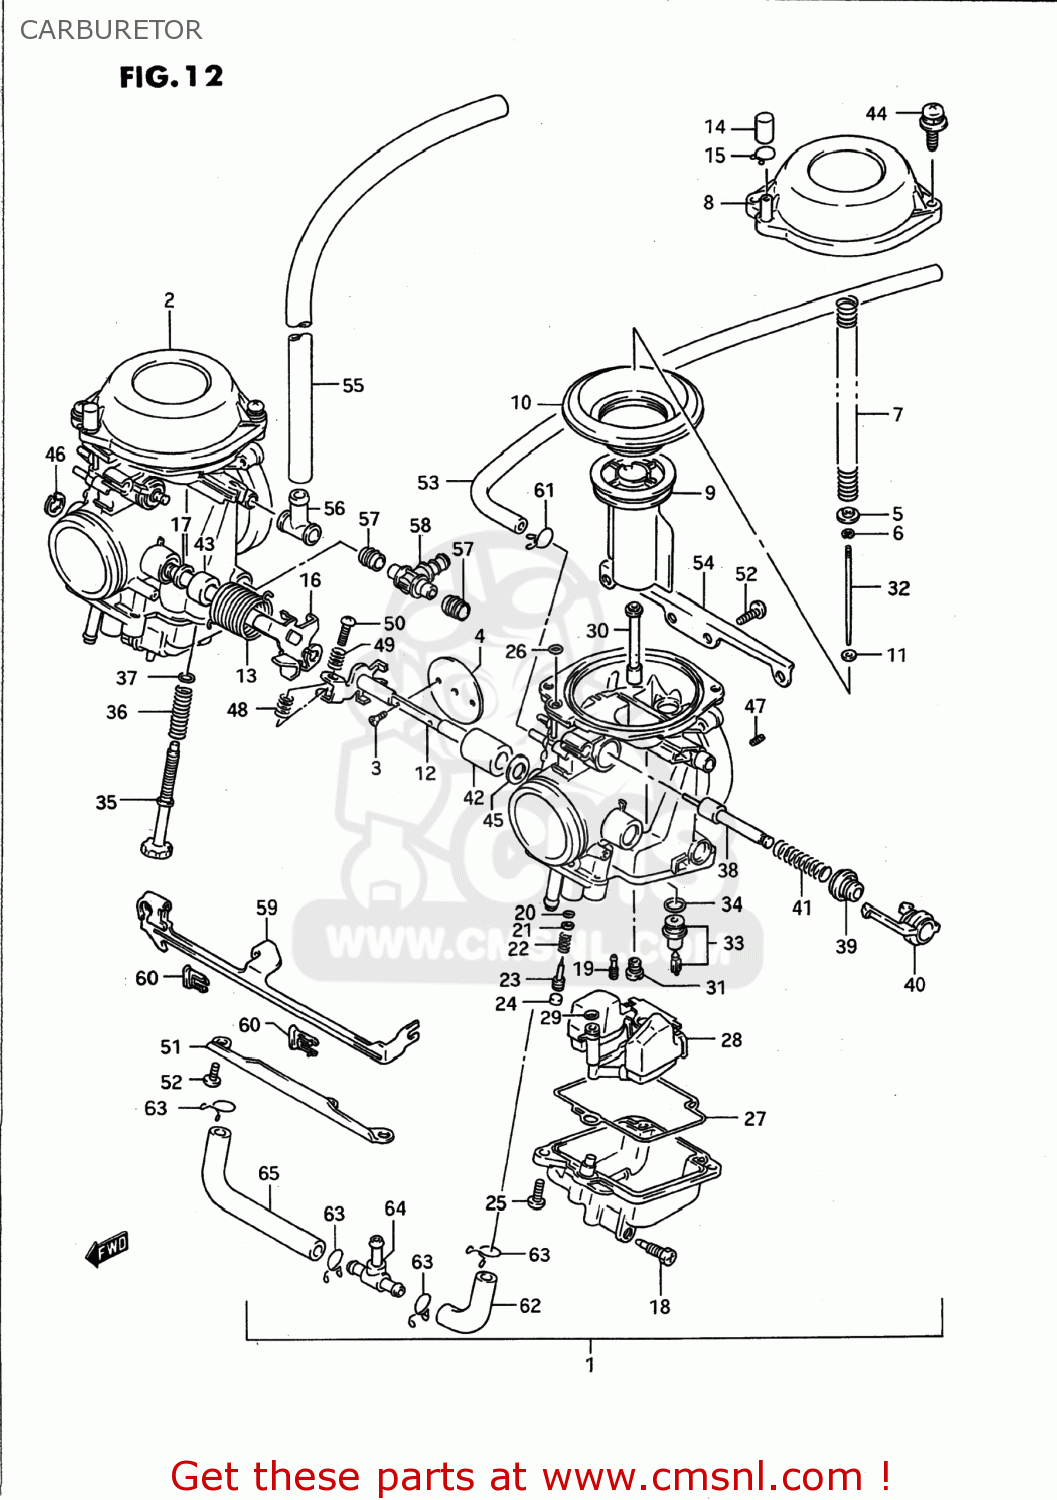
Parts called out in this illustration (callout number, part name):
1	CARBURETOR ASSEMBLY
2	CARBURETOR ASSEMBLY
3	SCREW
4	VALVE,THROTTLE(120)
5	RING
6	CLIP
7	SPRING
8	COVER,DIAPHRAGM
9	VALVE,PISTON
10	DIAPHRAGM
11	RING
12	SHAFT ASSEMBLY
13	SPRING
14	CAP
15	CLIP
16	SHAFT ASSEMBLY
17	SEAL
18	SCREW
19	JET,PILOT(37.5)
20	O RING,PILOT AIR SCREW
21	WASHER
22	SPRING
23	SCREW,PILOT
24	PLUG
25	SCREW
26	O RING
27	GASKET,FLOAT CHAMBER (NAS)
28	FLOAT ASSEMBLY
29	O RING
30	JET,NEEDLE (O-3)
31	JET,MAIN(122.5)
32	NEEDLE,JET
33	VALVE ASSEMBLY,NEEDLE
34	O-RING,NEEDLE VALVE
35	SCREW
36	SPRING
37	WASHER
38	PLUNGER ASSY
39	CAP,STARTER
40	HOLDER,GUIDE
41	SPRING
42	RING
43	RING
44	SCREW
45	GASKET,THROTTLE SHAFT (NAS)
46	E RING
47	JET,AIR(1.3)
48	SPRING,THROTTLE SCREW
49	SPRING
50	SCREW
51	PLATE
52	SCREW
53	HOSE(5X9X350)
54	PLATE
55	HOSE
56	HOSE
57	SEAL
58	NIPPLE
59	LEVER
60	HOLDER
61	CLIP
62	HOSE
63	CLIP
64	NIPPLE
65	HOSE
